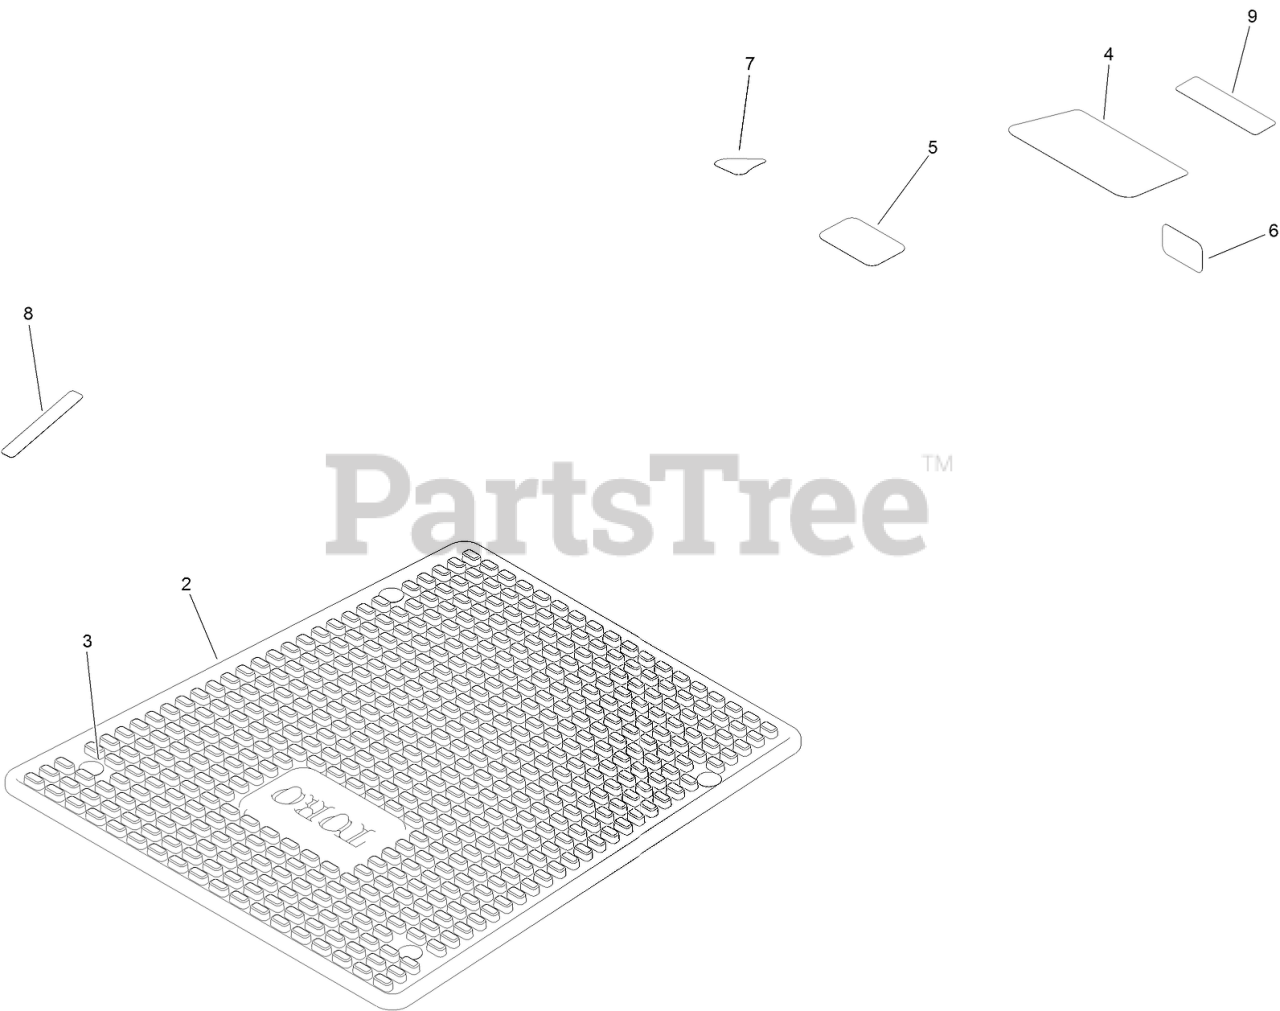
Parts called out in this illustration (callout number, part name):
2	MAT-FLOOR
3	PLUG-PLASTIC
4	DECAL-ENGINE
6	PLACARD-INTAKE
7	DECAL-DRAIN, OIL
8	DECAL-SHUTDOWN
9	DECAL-BUCKET
